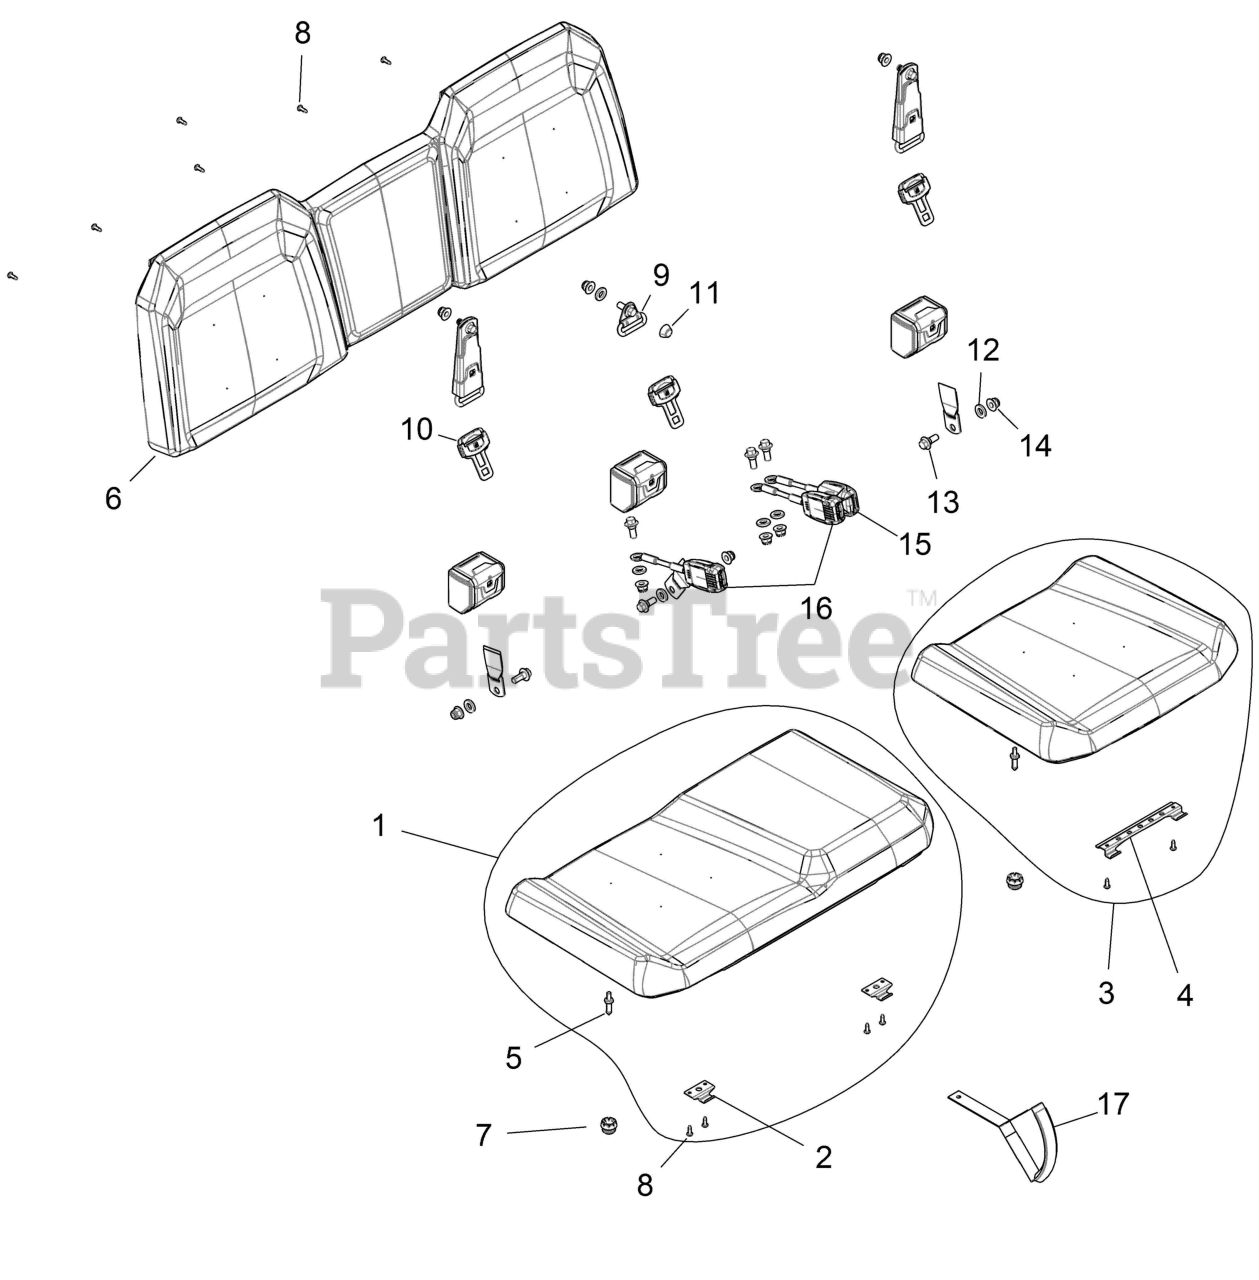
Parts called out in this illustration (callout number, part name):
1	ASM-SEAT,BTM,60,GRAVELY GRAY
2	BRKT-SEAT HINGE
3	ASM-SEAT,BTM,40,GRAVELY GRAY
4	BRKT-SEAT HINGE,DOUBLE
5	PIN-SEAT LATCH
6	ASM-SEAT,3PASS,BACK,GRVLY GRAY
8	SCR-TX TRUSS-#14X3/4,HI/LO ZBK
9	ASM-SEAT BELT,3PT,CENTER
10	ASM-SEAT BELT,3PT
11	CAP-BOLT HEAD
12	WASHER-SEATBELT,RUBBER
13	SCR-HXFLSH-M12X1.75-M14X9 ZOD
14	NUT-HXFL M12X1.75 NYLOC ZOD
15	BUCKLE-SEATBELT,9.6,DRIVER
16	BUCKLE-SEATBELT,9.6,PASSENGER
17	STRAP, SEAT, CENTER
